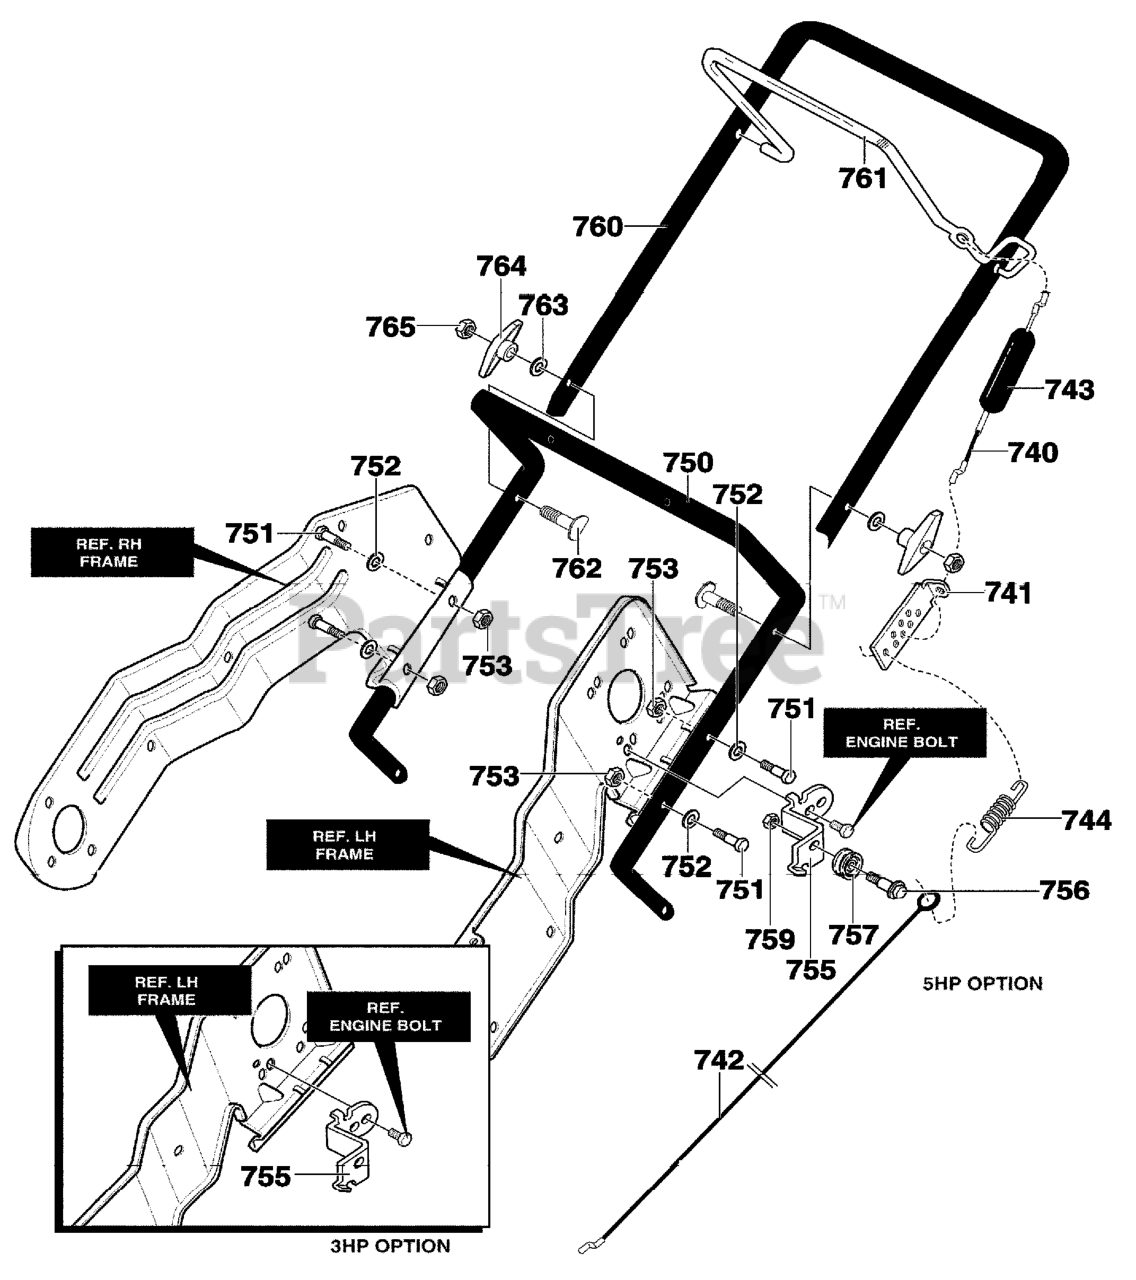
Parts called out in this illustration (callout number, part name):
740	CABLE, UPPER
741	BRKT, CABLE ADJ
742	CABLE LOWER CONTROL
743	BOOT, CLUTCH SPRING
750	HANDLE LOWER
751	SCREW, 1/4-20X1.25
752	WASHER, FLAT .281X.63X.065
753	NUT, 1/4-20 REGHEXCTRLK
755	BRACKET, CABLE
756	BOLT, .375X.375 1/4-20
757	PULLEY, .906X.305
759	NUT, 1/4-20 REGHEXCTRLK
760	HANDLE & FOAM, UPPER
761	BAIL, CONTROL
762	BOLT, 5/16-18X2.00
763	WASHER, FORM
764	KNOB,T
765	NUT, 5/16-18 REGHEX
